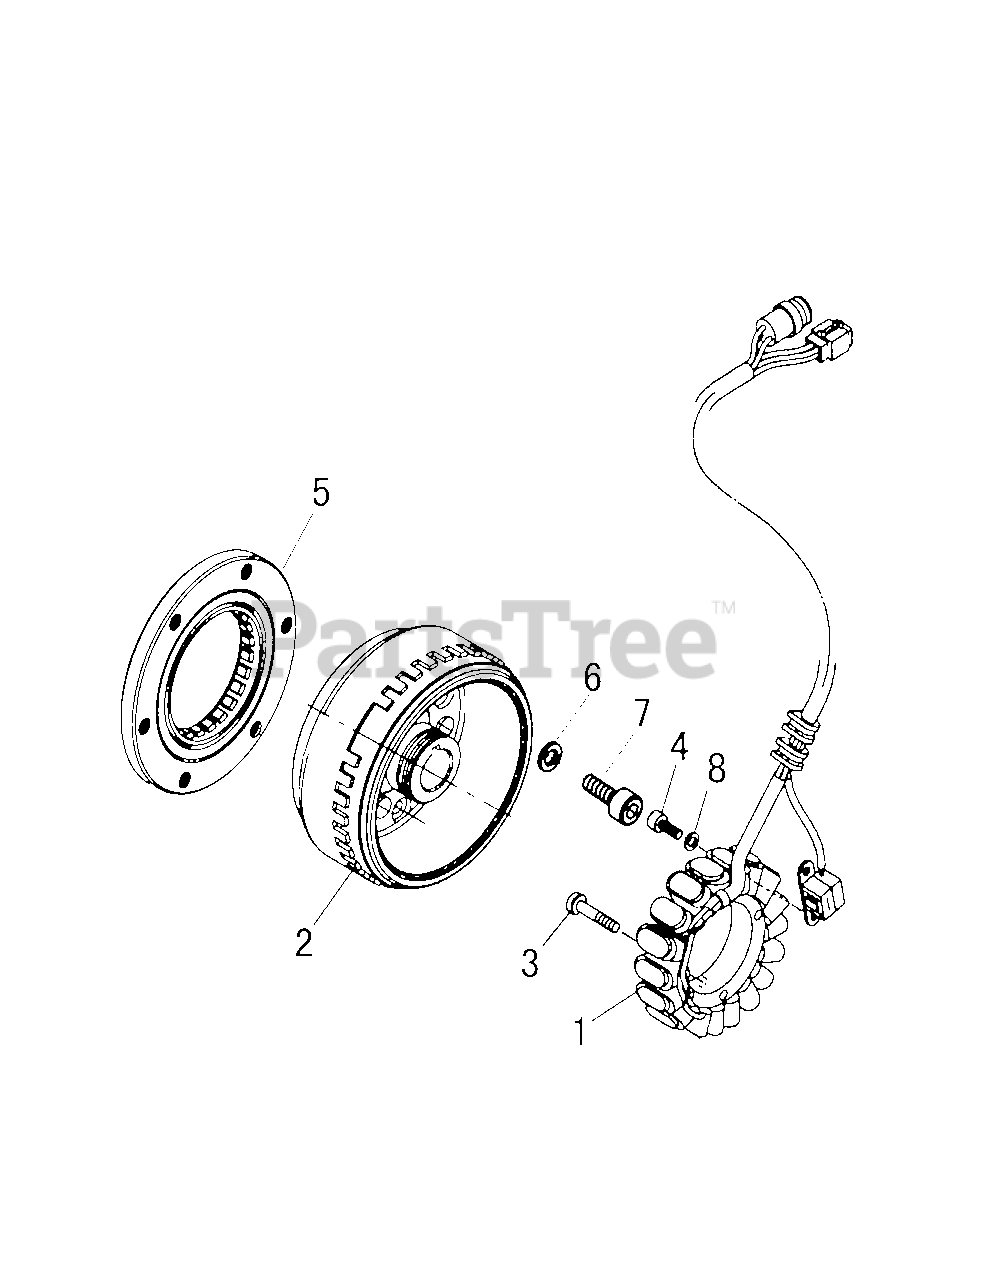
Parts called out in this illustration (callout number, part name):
1	Stator-Comp
2	Rotor-Comp
3	Flange Bolt M6X30
4	Screw-Hex Head M5 X 12
5	One Way Starter-Comp
7	Screw-Hex Head M8 X 16
